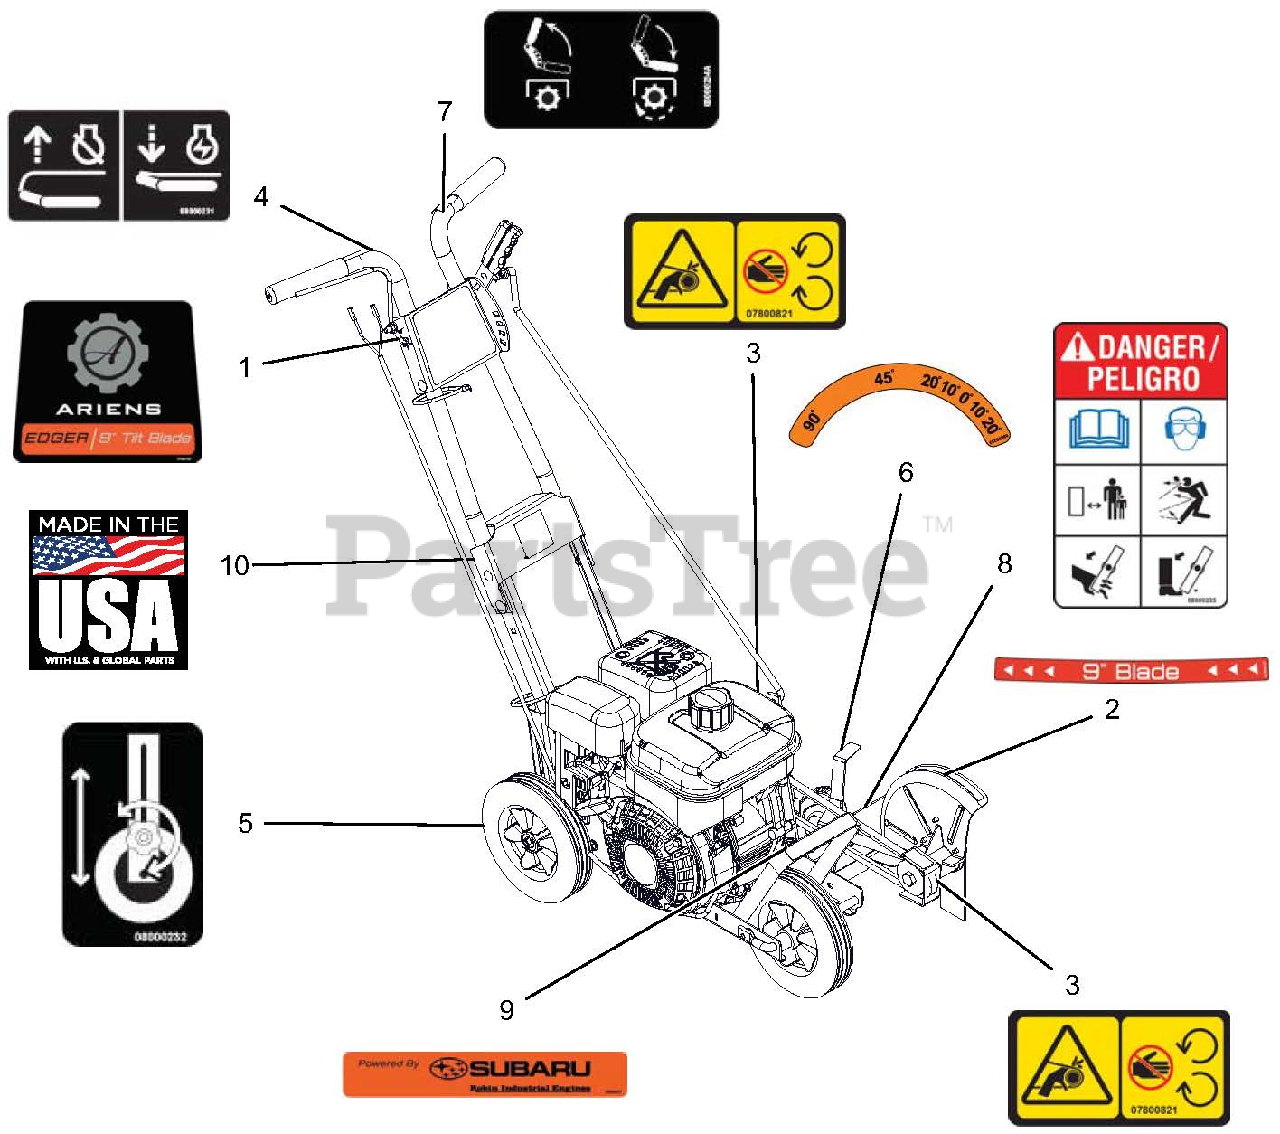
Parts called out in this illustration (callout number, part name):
1	DECAL-ARIENS EDGER
2	DECAL-9" BLADE
3	DECAL-SAFETY-GUARDING
4	DECAL, EDGER OPC
5	DECAL, EDGER DROP WHEEL
6	DECAL, EDGER BLADE TIP
7	DECAL, EDGER DEPTH CONTROL
8	DECAL, EDGER WARNING
9	DECAL, SUBARU
10	DECAL, MADE IN USA
